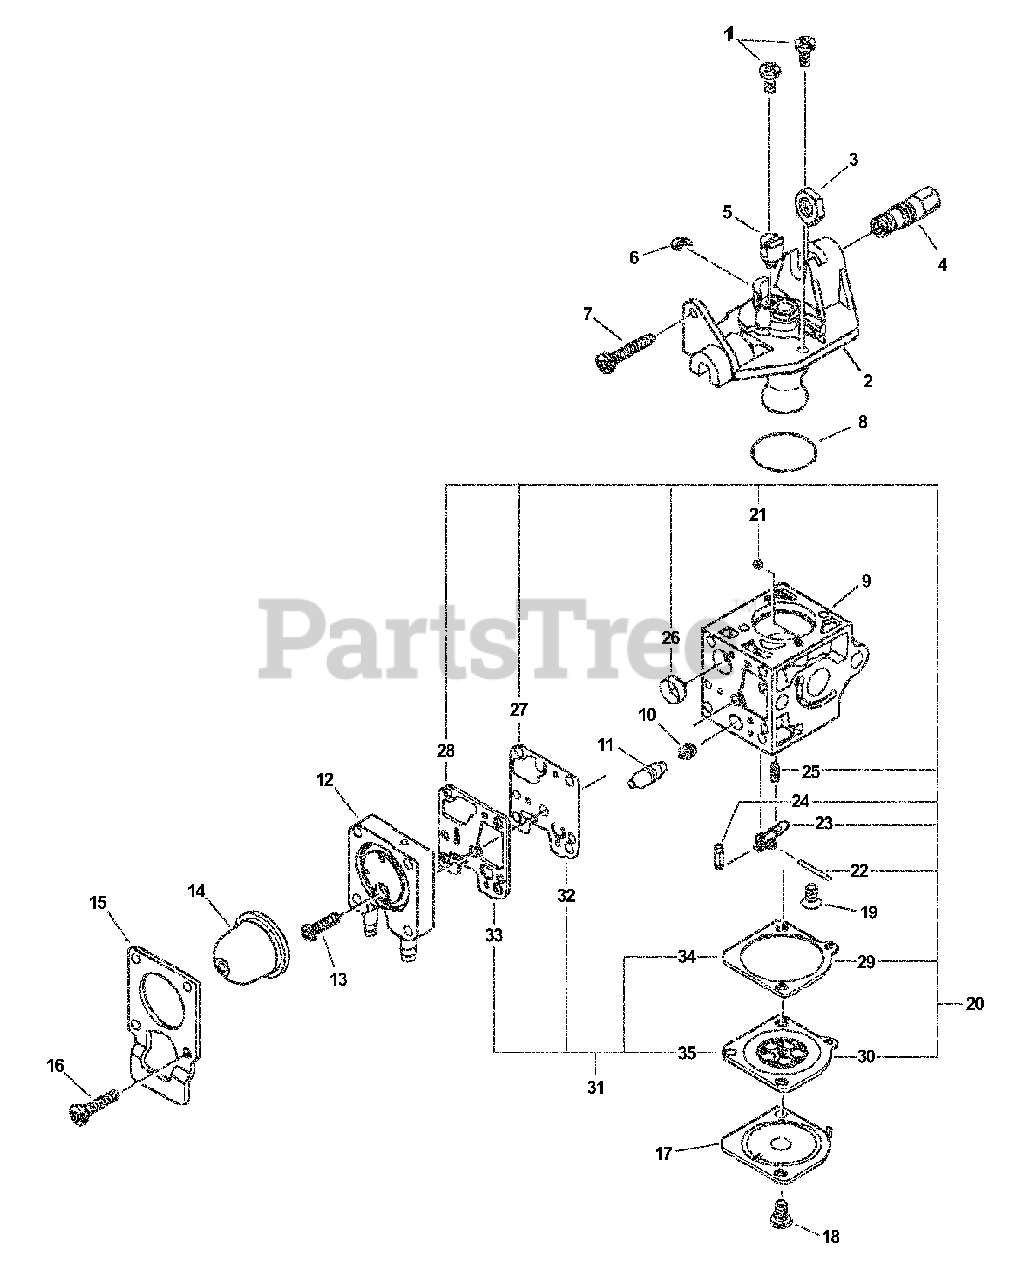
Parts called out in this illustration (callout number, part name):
2	ROTOR COVER ASSY
4	NUT, CABLE ADJUST
6	RING, RETAINING
7	SCREW, IDLE ADJUST
9	BODY, CARBURETOR
11	PLUG KIT
12	BASE, PURGE
13	SCREW, PURGE BASE
14	BULB, PURGE
15	RETAINER, PURGE BULB
16	SCREW, RETAINER
17	COVER, METERING
19	SCREW, METERING LEVER PIN
20	REPAIR KIT
21	GUIDE, ROLLER
22	PIN, METERING LEVER
23	LEVER, METERING
24	VALVE, INLET NEEDLE
25	SPRING, METERING LEVER
26	STRAINER
27	DIAPHRAGM, PUMP
28	GASKET, PUMP
29	GASKET, METERING
30	DIAPHRAGM, METERING
31	DIAPHRAGM/GASKET KIT
32	DIAPHRAGM, PUMP
33	GASKET, PUMP
34	GASKET, METERING
35	DIAPHRAGM, METERING
